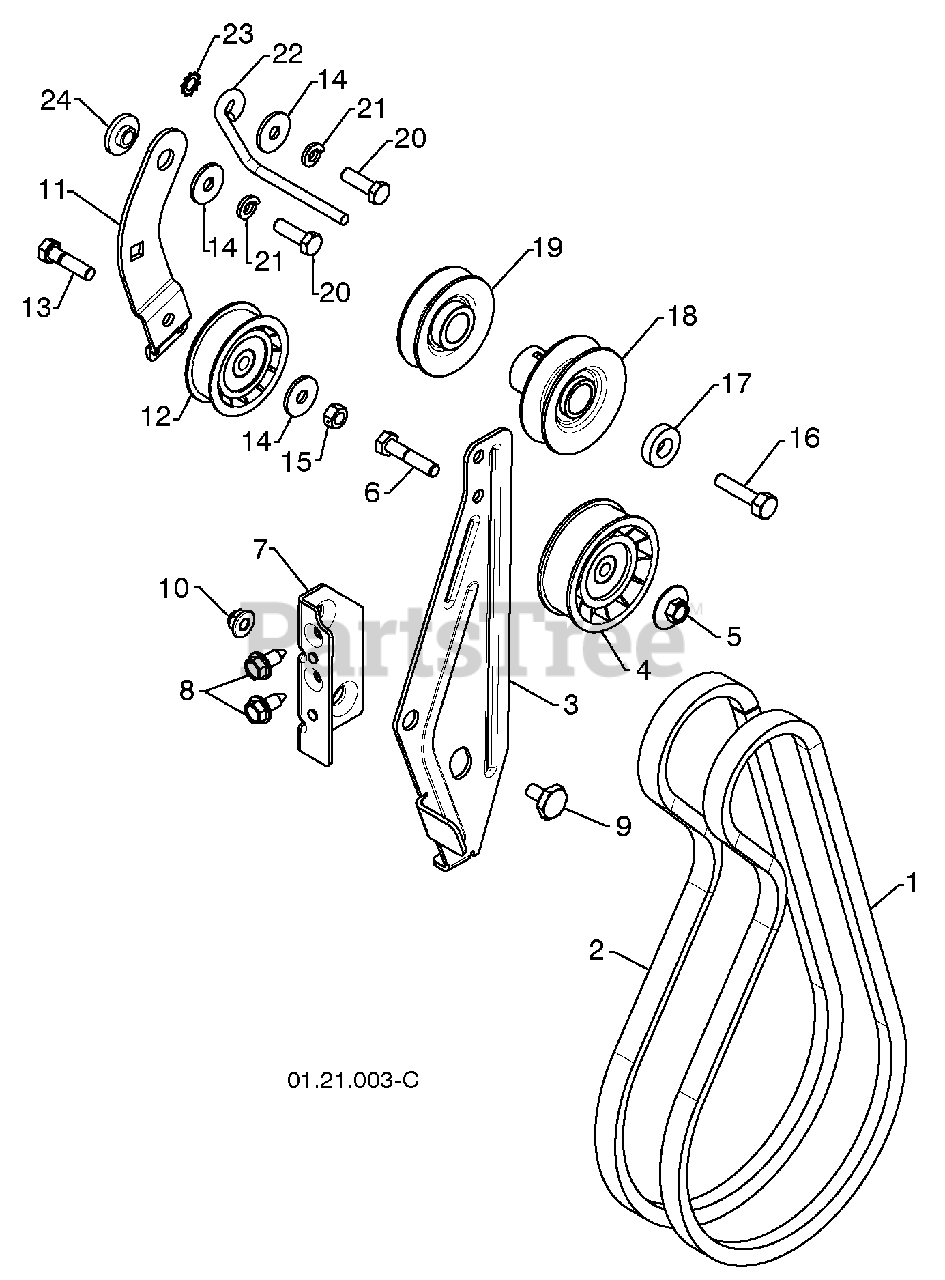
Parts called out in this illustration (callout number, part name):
1	IMPELLER BELT
2	TRACTION BELT
3	IDLER ARM BRACKET
4	IDLER PULLEY
5	NUT 5/16-18
6	SCREW 5/16-18 X 1 .50
8	SCREW 5/16-18 X .625
9	SHOULDER BOLT 5/16-18 X .500
10	NUT 5/16-18 NYLOCK
11	TRACTION IDLER ARM
12	TRACTION PULLEY
13	SCREW 5/16-18 X 1 .00
14	WASHER
15	NUT 5/16-18
16	SCREW 3/8-24 X 1.375
17	WASHER
18	PULLEY ENG IMPELLER
19	PULLEY ENG TRACTION
20	SCREW 5/16-18 X 1 .00
21	LOCKWASHER 5/16
22	BELT GUIDE
23	LOCKWASHER 5/16
24	IDLER BUSHING
